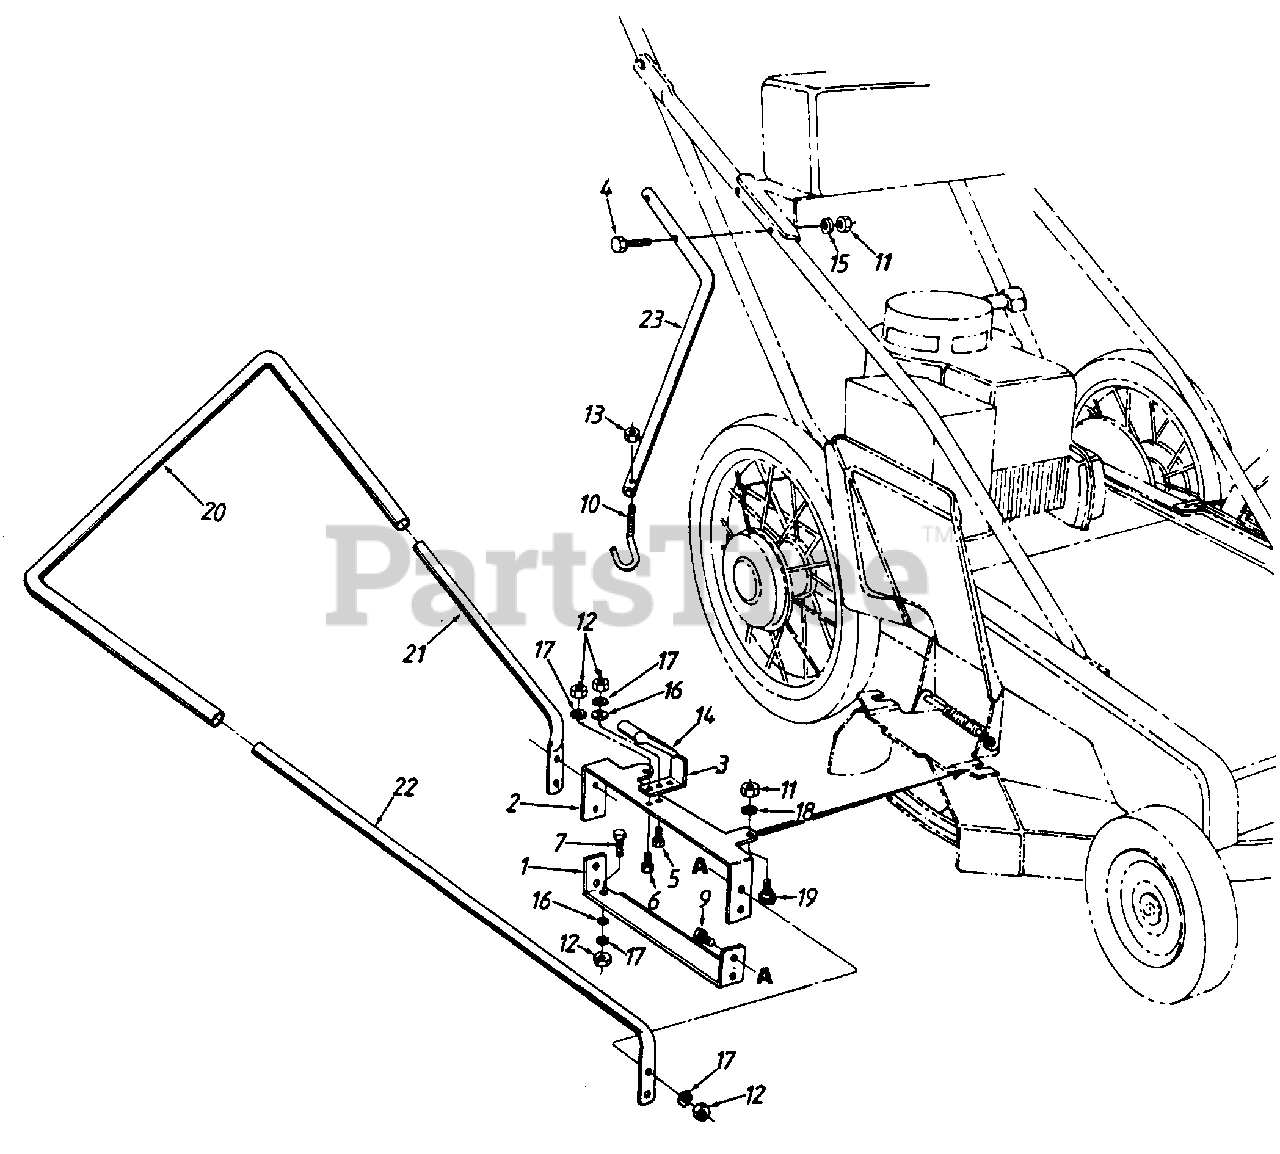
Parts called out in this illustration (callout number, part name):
1	SUPPORT-LOWER
2	SUPPORT-UPPER
3	BRACKET-HANDLE
4	SCREW-HEX 5/16-18 X 2.00
5	SCREW-HEX 1/4-20 X .75
6	SCREW-HEX 1/4-20 C .62
7	SCREW-HEX 1/4-20 X .50
9	SCREW-HEX 1/4-20 X 1.25
10	HOOK-CHAIN
11	NUT-HEX 5/16-18
12	NUT-HEX 1/4-20
13	NUT-INS LOCK 1/4-20
14	GRIP-FL BAR-END
15	WASHER-LOCK-5/16
16	WASHER-FL-.281 ID X .50 OD X .063
17	WASHER-EXTERN L 1/4
18	WASHER-EXTERN L 5/16
19	SCREW-SHLD .437 DIA X .350
20	FRAME-UPPER
21	FRAME-LOWER
22	FRAME-ARM-LOWER
23	ARM-HOLDING
